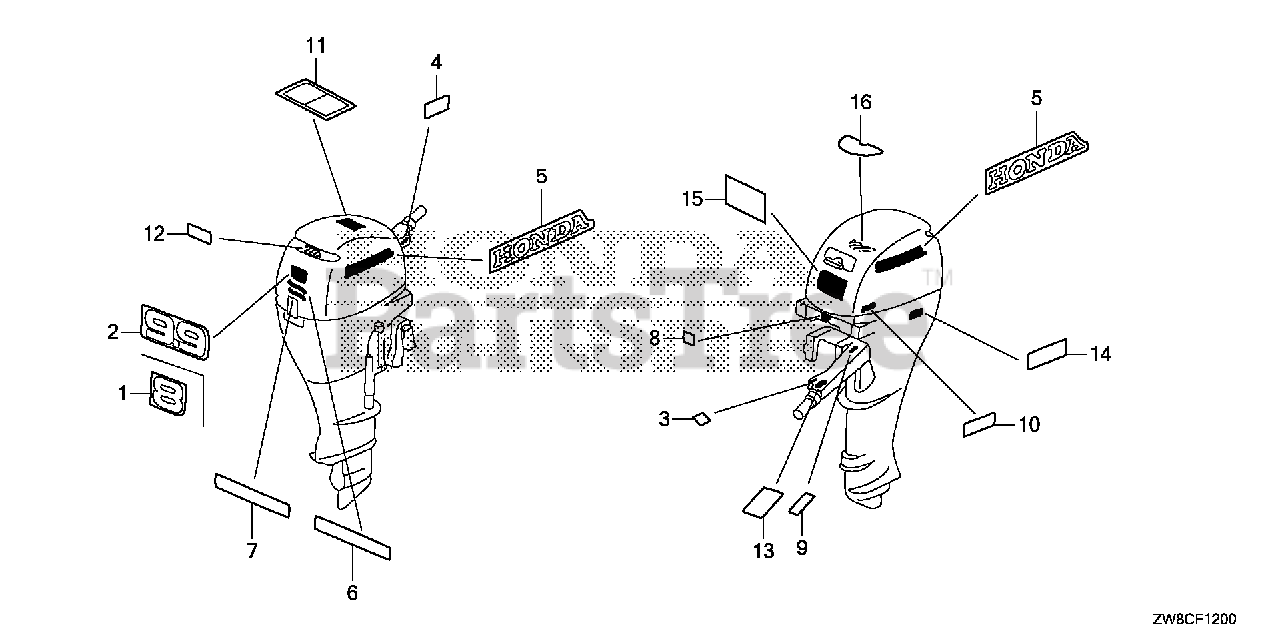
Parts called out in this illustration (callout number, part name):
1	MARK, RR. (8)
3	MARK, EMERGENCY SWITCH INDICATION (EU)
4	MARK, STARTER (ENGLISH)
5	MARK, SIDE STRIPE (HONDA)
6	MARK, POWER THRUST
7	MARK, POWER TILT
8	MARK, OIL PRESSURE
9	MARK, CHANGE (JAPANESE/ENGLISH)
12	LABEL, OIL CAUTION (ENGLISH)
13	MARK, THROTTLE (ENGLISH)
14	LABEL, STORING CAUTION (ENGLISH)
15	LABEL, CAUTION OPERATOR (ENGLISH)
16	MARK, EMERGENCY STARTER (ENGLISH)
